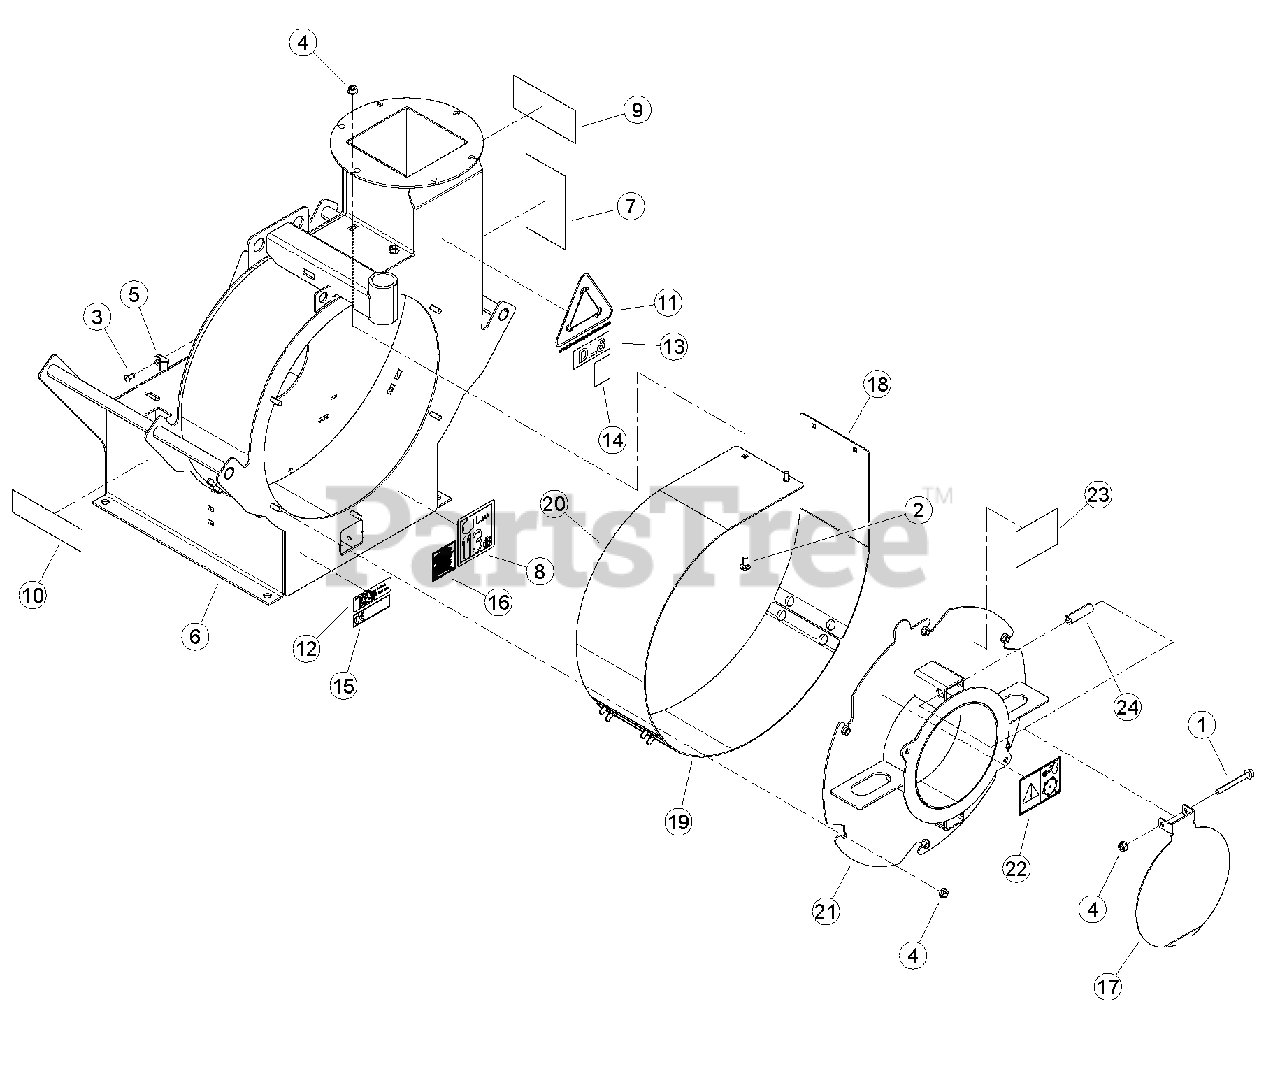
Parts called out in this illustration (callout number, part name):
1	BOLT, 5/16 X 3 FLANGE NC
2	BOLT, 5/16 X 3/4 GR5 CRG NC ZP
3	RIVET, AL BLIND 1/4 X 3/4 DOME HEAD
4	NUT, 5/16-18 NYLOCK FLANGE
5	CLAMP, CABLE MOUNT
6	ASSEMBLY, DL8 HOUSING
7	DECAL, OPERATING INSTRUCTIONS ISO
8	DECAL, 113 DB
9	DECAL, MULTILINGUAL MANUAL
10	DECAL, ECHO BEARCAT 6.82 X 1.90
11	DECAL, COLLECT IT
12	DECAL, ATLANTIC BRIDGE LTD INFO
13	DECAL, MODEL DL8
14	DECAL, ECHO BEARCAT QR CODE
15	DECAL, DL8 INFORMATION
16	DECAL, SPARK ARRESTOR
17	SHIELD, INTAKE
18	LINER, WEAR RIGHT
19	LINER, WEAR MIDDLE
20	LINER, WEAR LEFT
21	ASSEMBLY, VACUUM INTAKE
22	DECAL, INSTRUCTION ISO
23	DECAL, INSTRUCTION ISO
24	SPACER, 5/8 OD X 11 GA X 2.13
